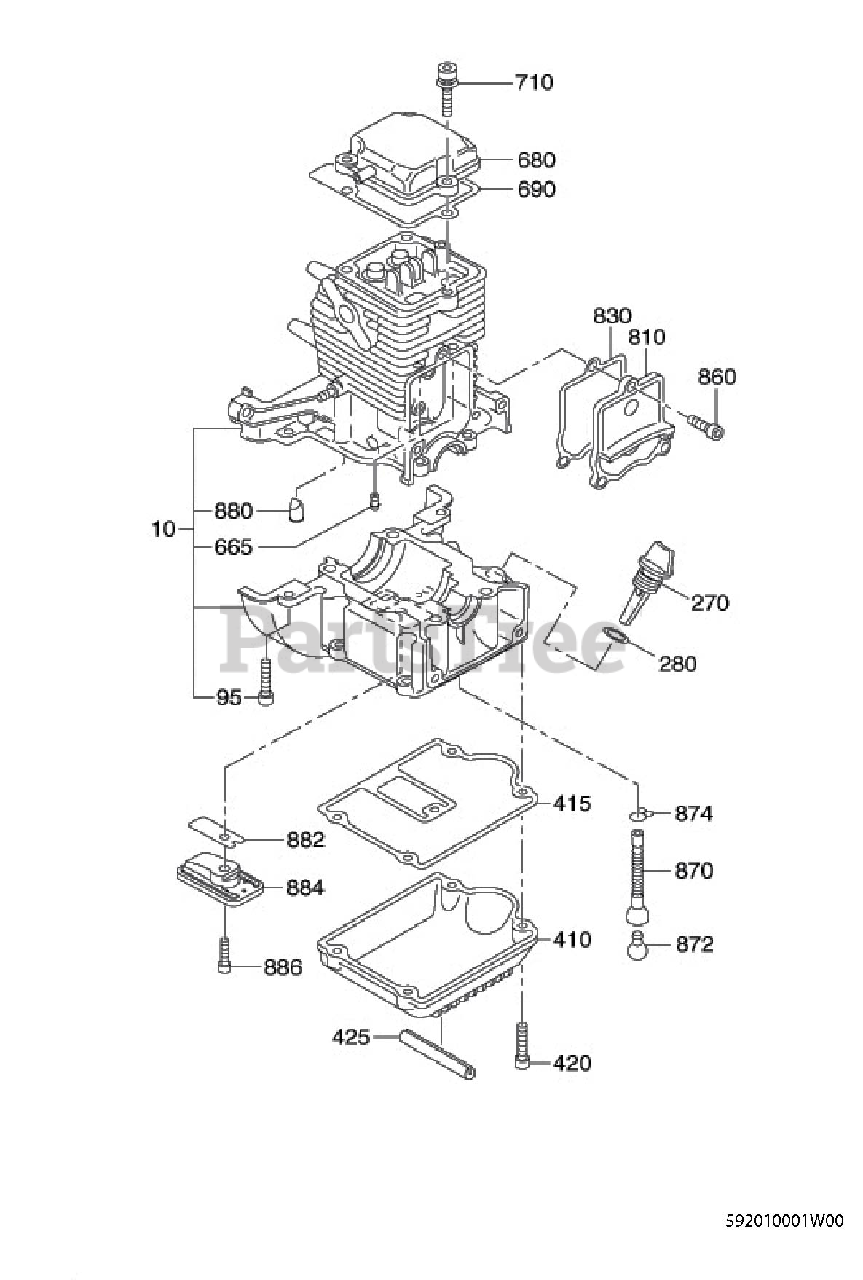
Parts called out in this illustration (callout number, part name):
10	CYLINDER BLOCK SET
95	H.S.H BOLT
280	GASKET
410	CASE,OIL
415	GASKET,CASE
420	H.S.H. BOLT
425	GUARD, CASE OIL
665	SPACER
680	ROCKER COVER CP
690	GASKET,ROCKER COVER
710	H.S.H. BOLT
810	CAM GEAR COVER
830	COVER CAM GEAR GASKET
860	H.S.H. BOLT
882	LEAD VALVE
884	RETAINER PLATE
886	SOCKET HEAD BOLT
